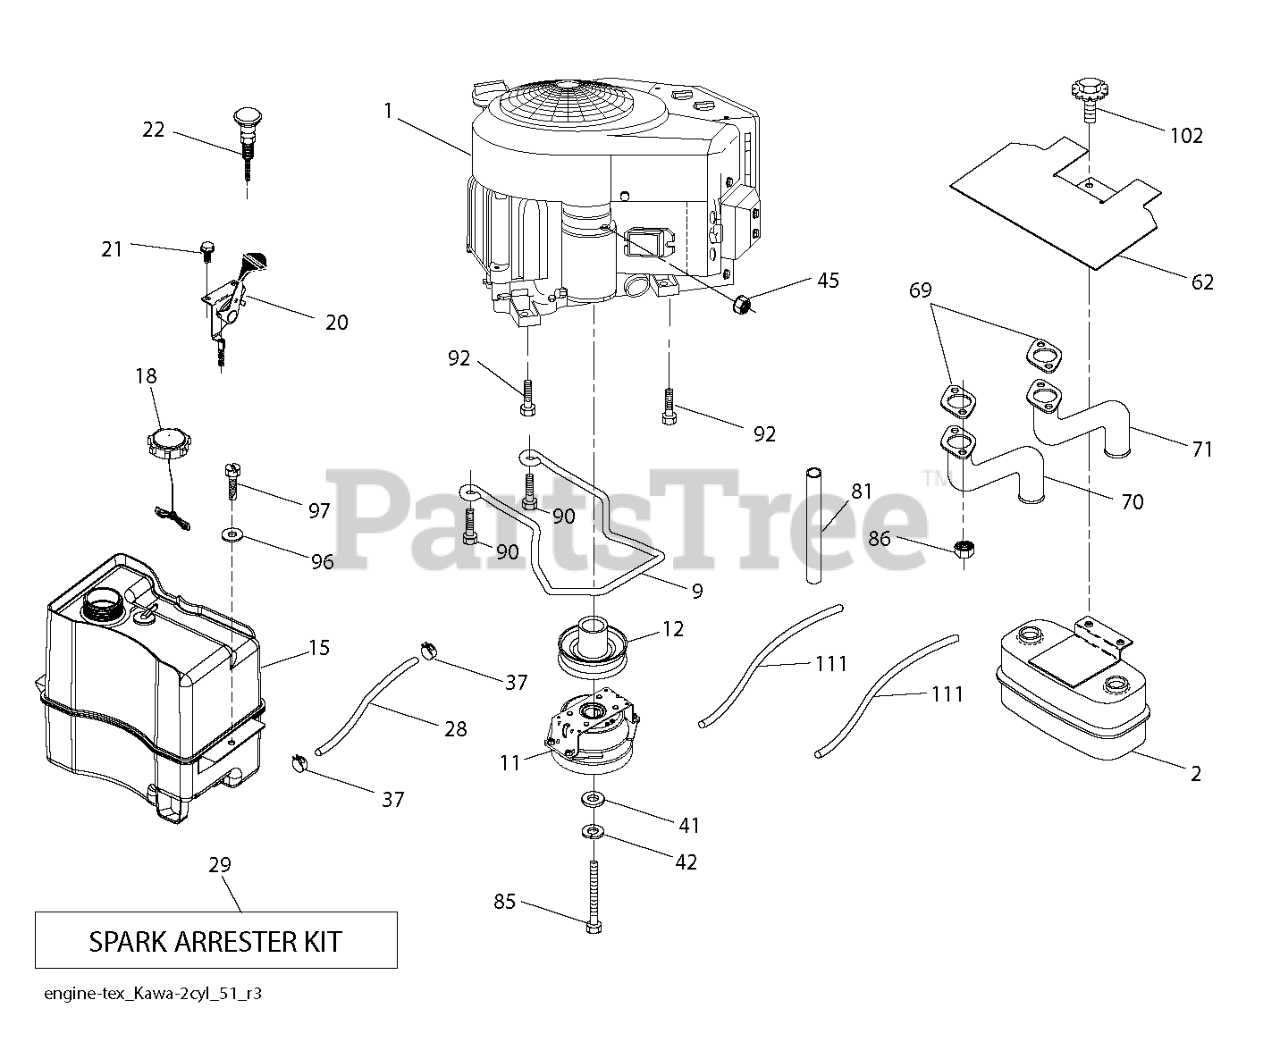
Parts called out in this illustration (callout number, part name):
2	MUFFLER.ASM.TWIN.MNTG.BRACKET
9	KEEPER.BELT.ENG.4.25"2.BLT.431
11	CLUTCH.OGURA.4.4PD.GT1.5-EH13V
12	PULLEY.ENGINE.TUFFTORQ
15	Tanks
18	FUEL.CAP.ASM.2.25TETHRED.RATCH
20	CONTROL.THROTTLE.COBRA.BLACK
22	CONTROL, CHOKE
28	LINE.FUEL.20"FRONT.EMI
29	KIT.SPARK ARRESTOR 794945 B&S
37	HOSE CLAMP
45	Hardware
62	SHIELD.HEAT.MUFFLER
70	TUBE.EXHAUST.RH.FR961/FR730
71	TUBE.EXHAUST.LH.FR961/FR730
81	TUBE, DRAIN OIL ASM.
85	CLUTCH BOLT7/16-20X3.5 GR524HR
86	NUT.HEX.FLANGE.TOPLOCK
90	SCREW 3/8-16X1
92	SCREW 3/8-16X1
97	SCREW HEXWSHR 1/4-20X3/4
102	SCREW
